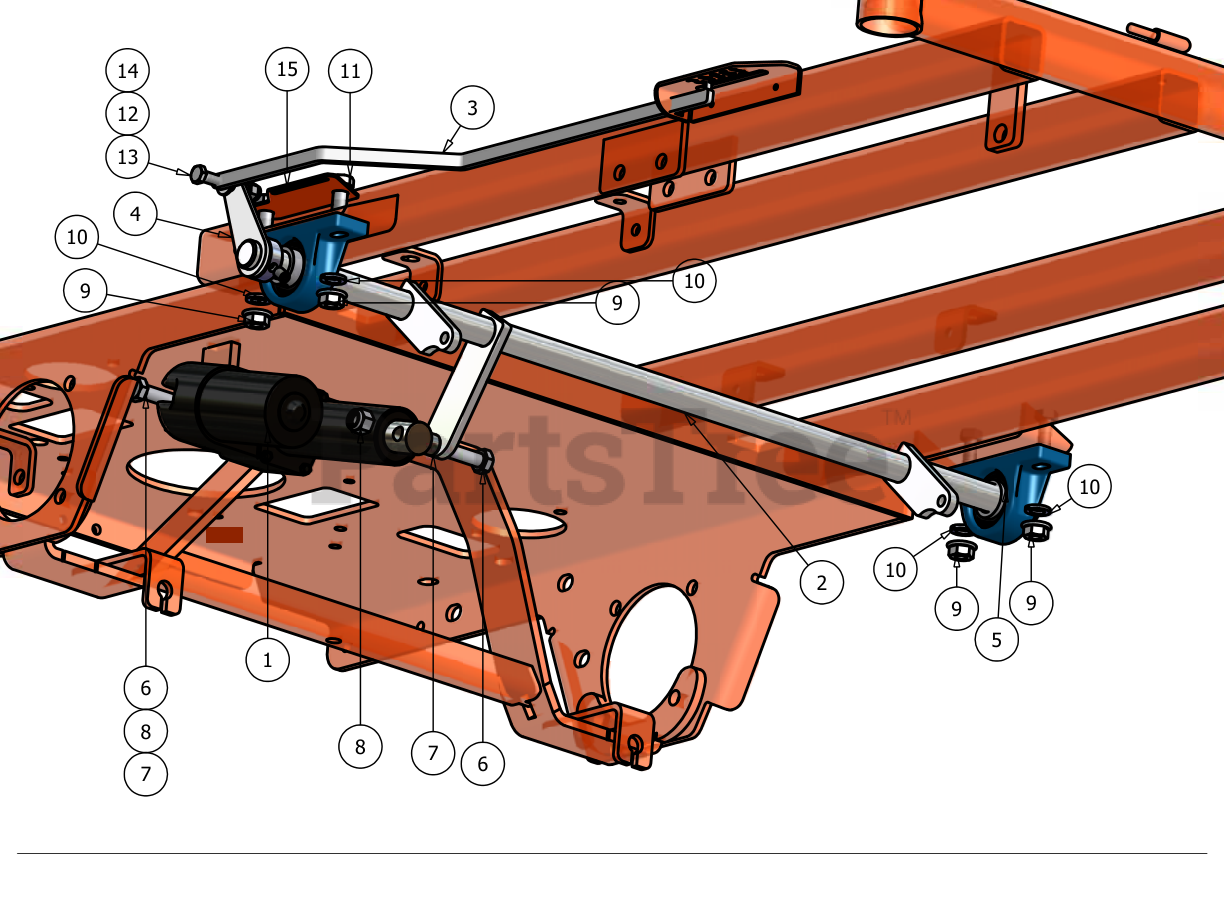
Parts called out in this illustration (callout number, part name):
2	Actuator Bar
3	Pup Height Indicator
4	Height Indicator Tab
5	1" Pillow Block
6	1/2" x 3" Hex Bolt
7	1/2" x 1/2" Collar Spacer
8	1/2" Nylock Nut
10	1/2" Lock Washer
11	1/2" x 1 1/2" Hex Bolt
12	3/8" Plastic Washer
13	3/8" x 1" Hex Bolt
14	3/8" Nylock Nut
15	Deck Stop Bracket
